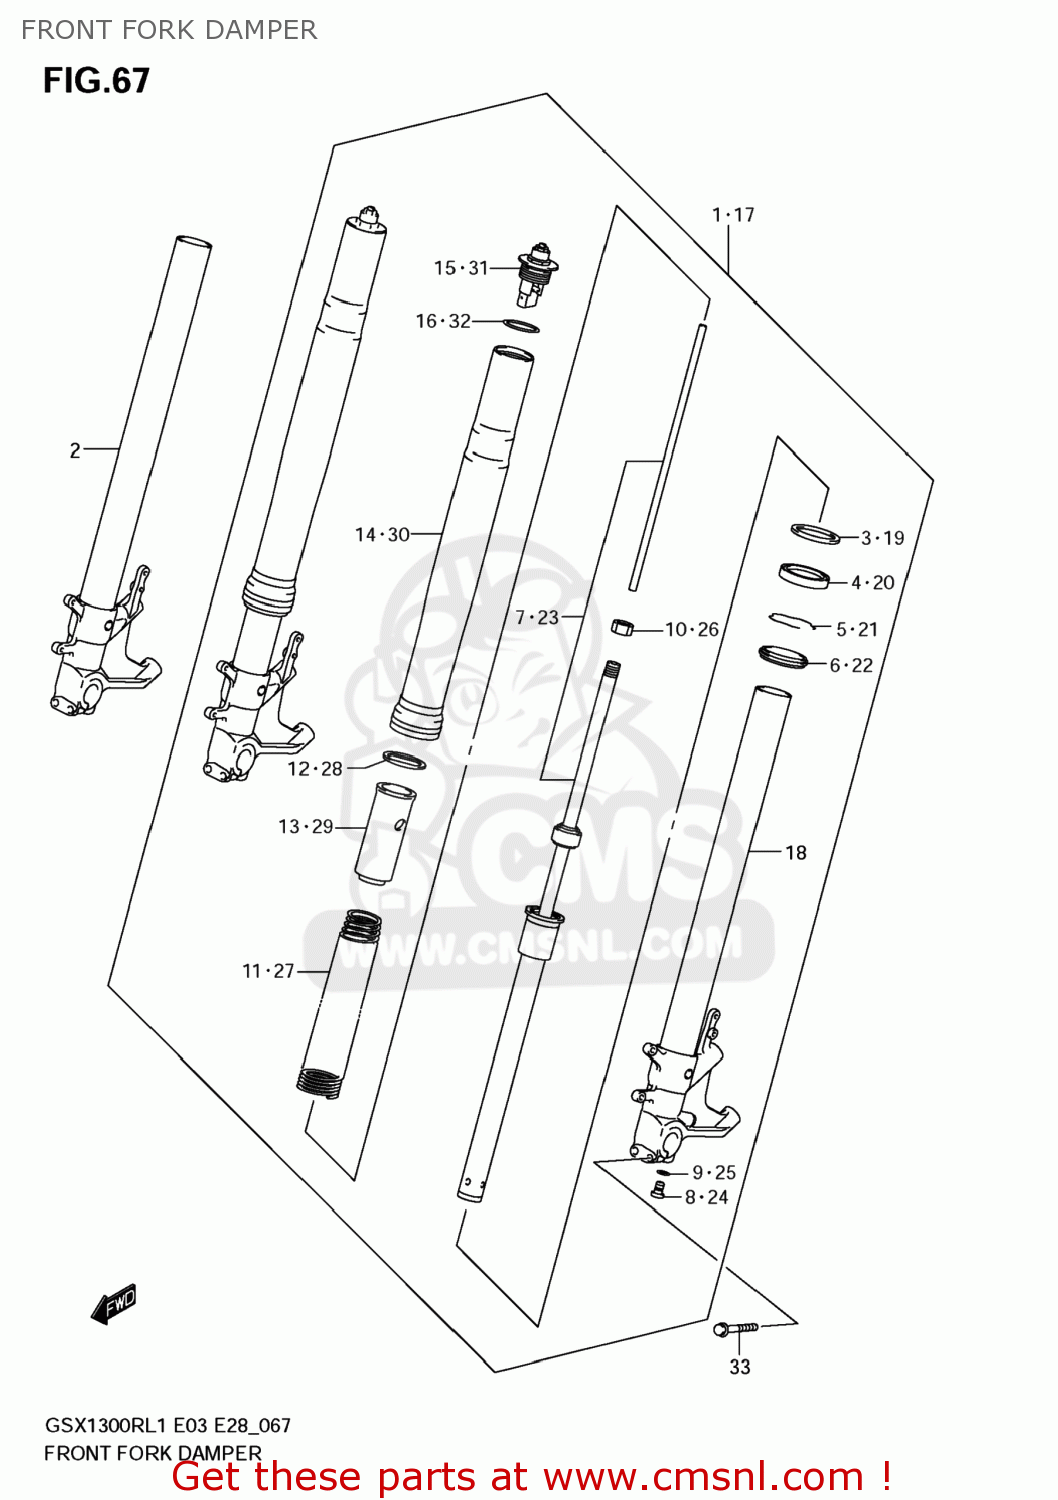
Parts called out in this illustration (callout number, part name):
1	DAMPER ASSY,FR FORK,R
2	TUBE,INNER,R
3	WASHER
4	SEAL,OIL
5	RING,STOPPER
6	SEAL,DUST
7	CYLINDER
8	BOLT
9	GASKET (NAS)
10	NUT,ROD
11	SPRING,FR
12	GUIDE,SPRING
13	SPACER,SPRING
14	TUBE,OUTER
15	CAP,FR FORK
16	O RING
17	DAMPER ASSY,FR FORK,L
18	TUBE,INNER,L
19	WASHER
20	SEAL,OIL
21	RING,STOPPER
22	SEAL,DUST
23	CYLINDER
24	BOLT
25	GASKET (NAS)
26	NUT,ROD
27	SPRING,FR
28	GUIDE,SPRING
29	SPACER,SPRING
30	TUBE,OUTER
31	CAP,FR FORK
32	O RING
33	BOLT
